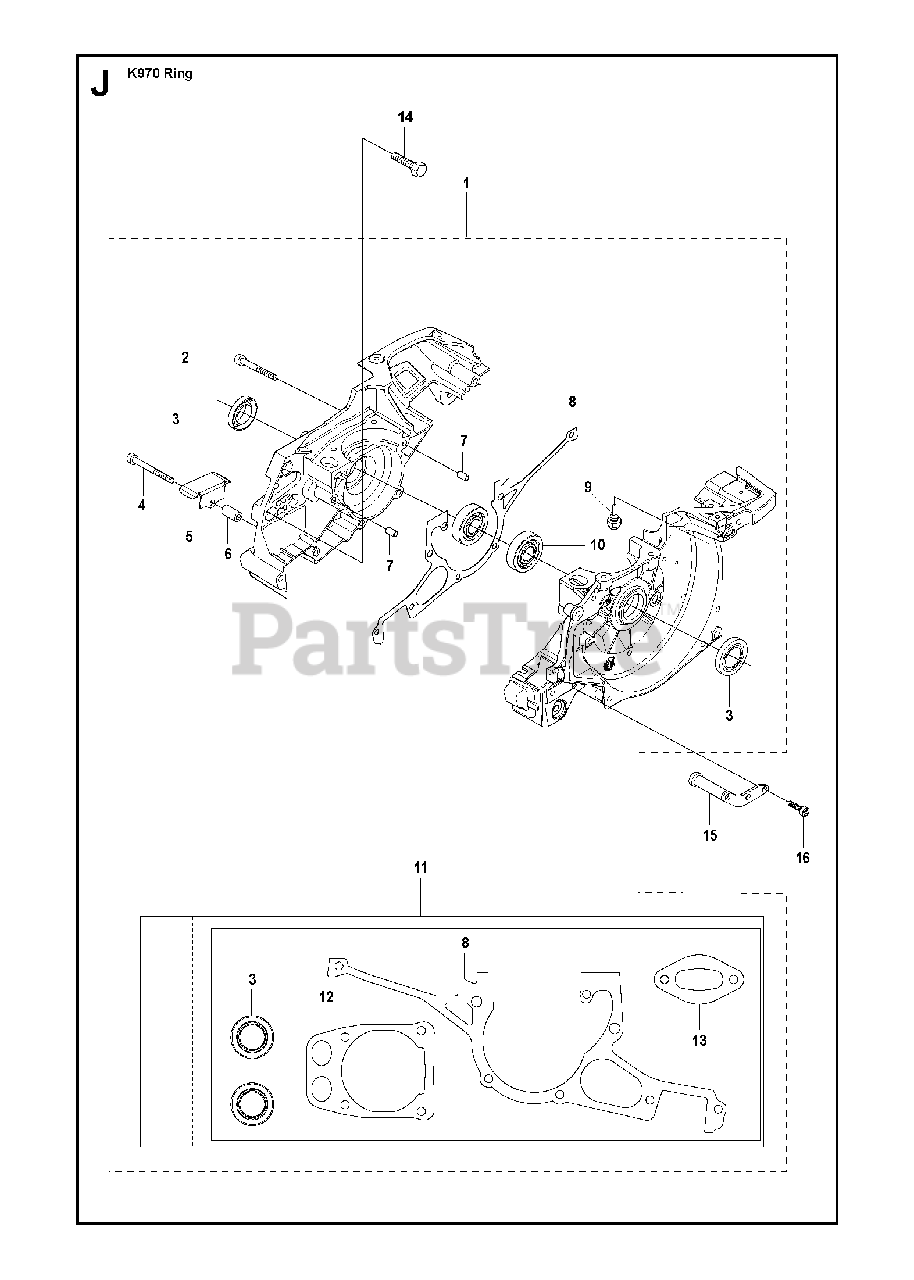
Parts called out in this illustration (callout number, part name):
1	CRANKCASE ASSYIncl. 2 - 11
2	SCREW ITXSCM
3	SEALING RING
4	SCREW ITXSCM
7	GUIDE BUSHING
9	RUBBER BUSHING
10	BALL BEARING
11	GASKET KITIncl. 3, 8, 12 - 13
13	GASKET
